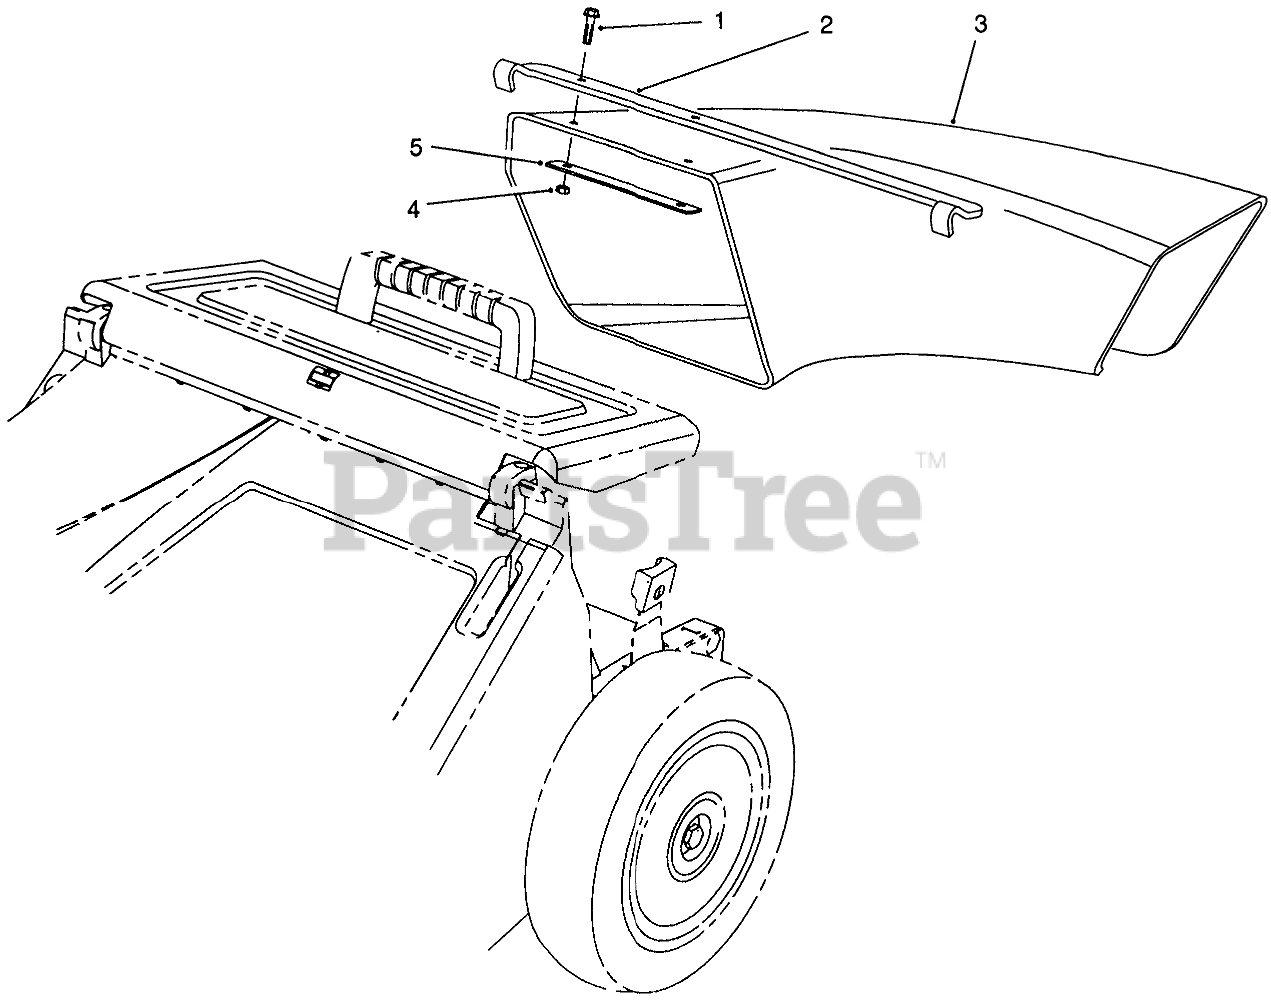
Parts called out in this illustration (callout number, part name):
1	SCREW-HWH
2	CHUTE HANGER BRACKET
3	Chute-Discharge
4	NUT-LOCK, NI
5	STRESS PLATE
